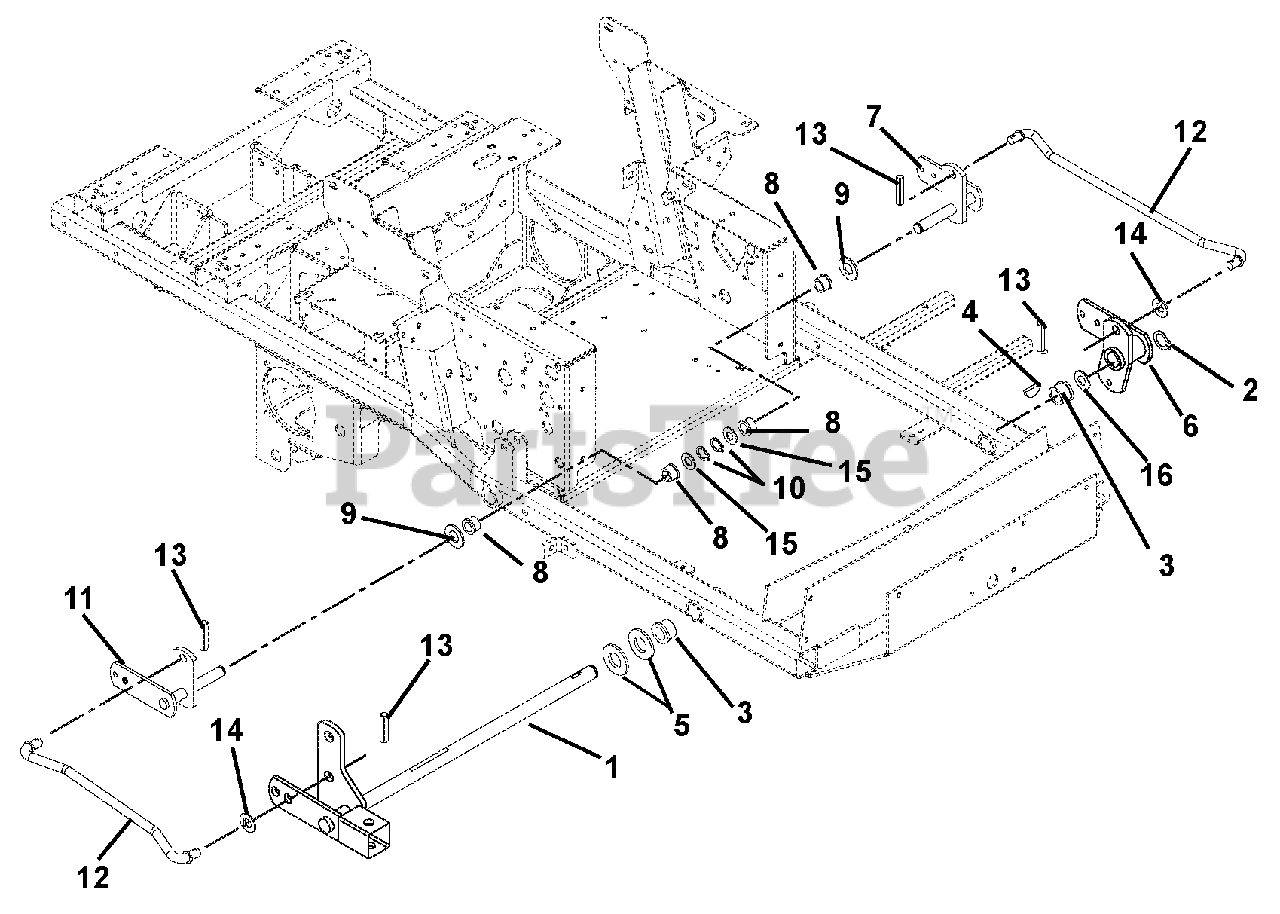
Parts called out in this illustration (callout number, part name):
1	WMT, FRONT MOWER LIFT (HYD)
2	RG-RTNG-EXT 1.00X.078
3	BSHG,1.00ID X 1.125OD X 1.50LG
4	KEY-WDRF .25X1.00 HRD #15
5	WSHR-FL-STL- 1.062X2.0X.134 YZ
6	WMT, LH FRONT MOWER LIFT
7	WMT-LH REAR LIFT ARM (DIESEL)
8	BSHG-FLG .762X1.0X.580X1.48 NY
9	WSHR-HDND-THRST .758X1.23X.031
10	RG-RTNG-EXT .689X.078
11	WMT-RH REAR LIFT ARM (DIESEL)
12	ROD, LIFT ASSIST 19.35"
13	PIN-ROLL .250X1.25 STNLESS STL
14	WSHR-FL-STL .630X1.250X.062 YZ
15	WSHR-FL-STL .755X1.25X.125 YZ
16	WSHR-HDND-THRUST 1.00X1.55X.03
